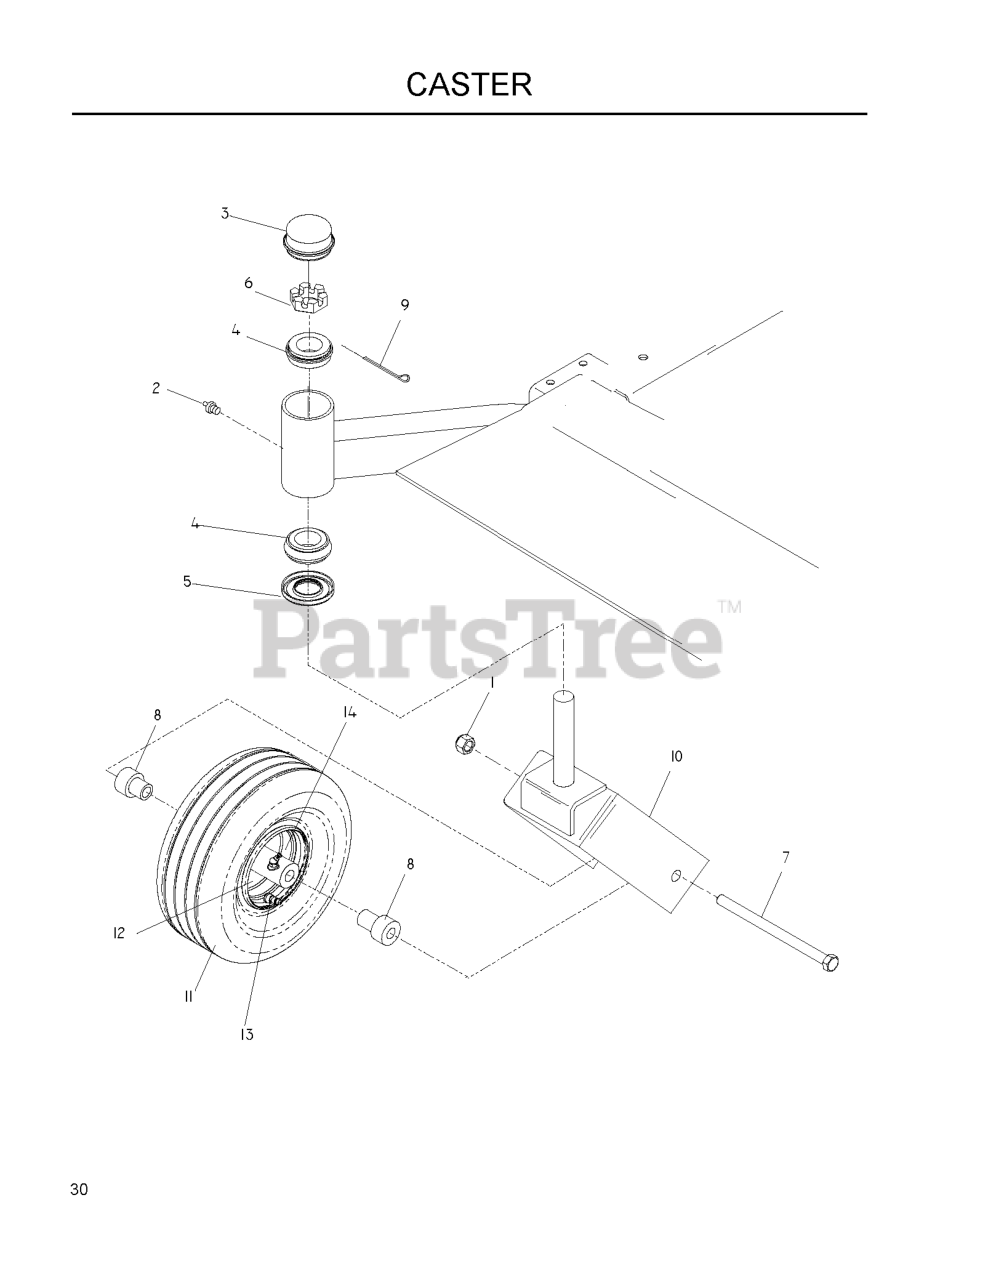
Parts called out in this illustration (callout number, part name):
1	NUT 1/2-13 HEX NYLOC ZD
2	ZERK
3	GREASE CAP
4	TAPERED ROLLER BRG
6	NUT 1"C HEX SLOTTED
7	HEX SCREW 1/2-13 X 9.5 GR5
8	AXLE SPACER
9	COTTER PIN 1/8 X 2
10	CASTOR YOKE ORANGE
11	FRONT TIRE ASSY
13	VALVE STEM TR-412
14	ZERK
